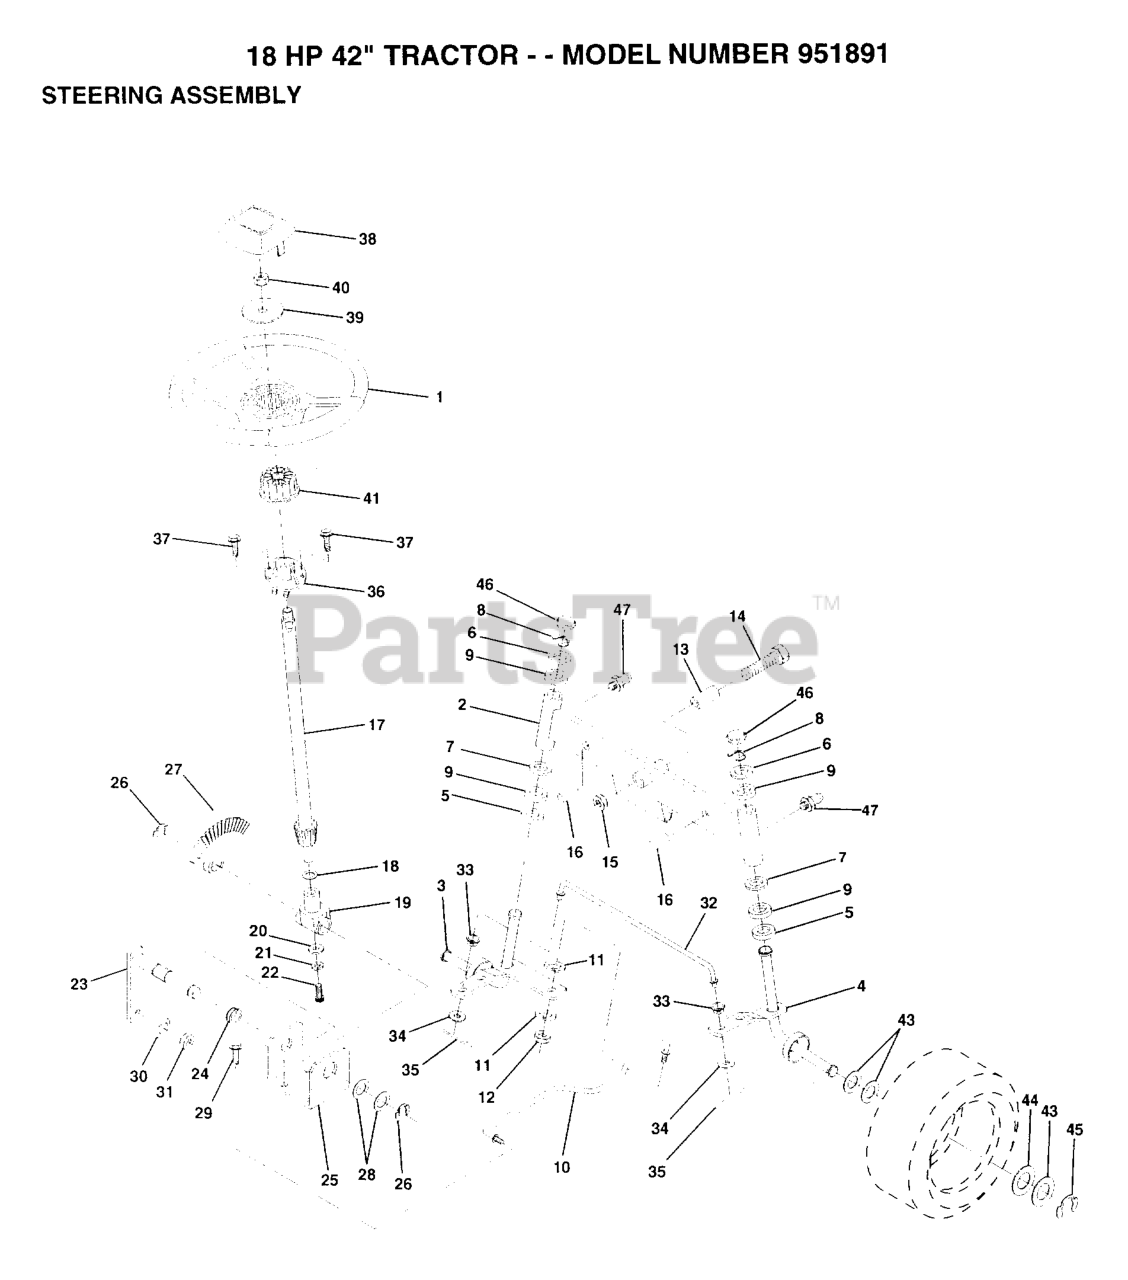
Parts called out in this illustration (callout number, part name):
3	SPINDLE LH
4	SPINDLE RH
5	WASHER .T
6	WASHER
7	WASHER
8	RING
9	COL. SRTG. BEAR.
11	LOCKWASHER
13	BEARING
14	BOLT HEX 5/8-11
15	"NUT-LOC,FLANGE LT"
16	AXLE PIN
17	STEERING SHAFT
18	THRUST WASHER
19	SUPPORT.SHAFT
21	LOCKWASHER
22	"SCREW,SPECIAL"
24	NYLINER T
25	"BRKT,STEERING"
26	RING
27	GEAR SECTOR
28	WASHER .T
29	SCREW
30	LOCKWASHER
32	TIE ROD
33	BUSHING.DRAGLINK
34	WASHER
35	COTTER PIN
38	ST WHL INSERT CAP
39	WASHER
41	ADAPTER LT
43	WASHER
44	WASHER
45	RING
46	CAP
47	ZERK M
